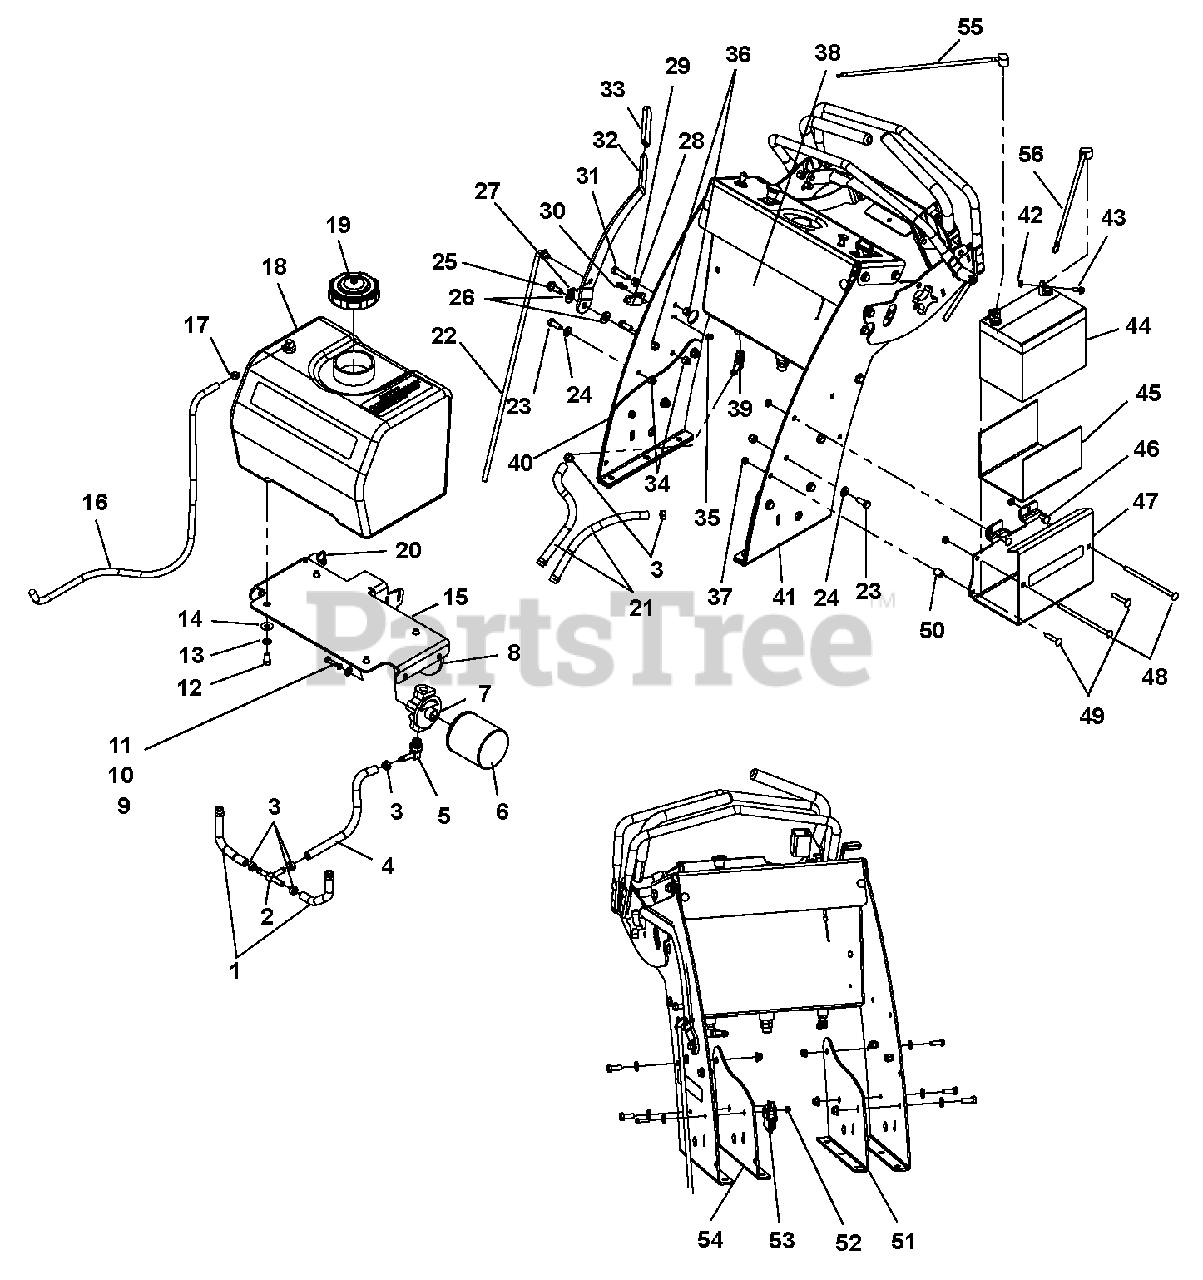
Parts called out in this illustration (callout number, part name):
1	Hose, Hydraulic .375 x 6.00
2	Fitting, TUN .375 Hose
3	Clamp, Hose - 1/2" Pinch
4	Hose, Hydraulic .375 x 10.5
5	Fitting, 90 Deg. Barb-OR
6	Filter, Oil
7	Head, Oil Filter
8	Guard, Hydraulic Filter
9	Washer, .250 Regular Flat
10	Washer, .250 Medium Spring Lock
11	Bolt, .25-20 x 1.00 Hex Grade 5
12	Bolt, .38-16 x .75 Hex Grade 5
13	Washer, .375 Medium Spring Lock
14	Washer, .375 Regular Flat
15	Bracket, Fuel Tank
16	Hose, Fuel .25 x 15.00
17	Clamp, Fuel Line
18	Fuel Tank, Rev B
19	Cap, Fuel
20	Cable Tie, .15 x 8.50
21	Hose, Hyd. .375 x 11.5
22	Rod, Drive Control
23	Bolt, .38-16 x 1.00 Hex Grade 5
24	Washer, .406 x .813 x .065 Flat
25	Bolt, .50 x 1.06 x .375-16 Grade 5
26	Washer, .510 x 1.00 x .068 Nylon
27	Ring, Rue .375 x .054 x 1.254
28	Switch- Double Pole N.O./N.O.
29	Locknut, .375-16 WHIZ
30	Screw, 10-24 x .625 Phillips Head
31	Bolt .38-16 x 1.50 Hex Grade 5
32	Lever, Hand Brake
33	Grip, PVC .250 x 1.00 x 3.63
34	Locknut, .375-16 Nyloc
35	Locknut, 10-24 Nyloc
36	Locknut, .375-16 Center
37	Locknut, .3125-18 Nyloc
38	Weldment, Hydraulic Tank
39	Fitting, 90 .5625 MOR x .375 Hose
40	Weldment, RH Upright Tower 18"
41	Weldment, LH Upright Tower 18"
42	Locknut, .25-20 (988402, 403)
43	Bolt, .25-20 x .625 (988402, 403)
44	Battery, 12V-U1-CCA270 (988402, 403)
45	Strip, Battery Insulator (988402, 403)
46	Bolt, Round Head Square Neck .31-18 x .75 Grade 5 (988402, 403)
47	Tray, Battery (988402, 403)
48	Bolt, .3125-18 x 6.00 Grade 2 (988402, 403)
49	Bolt, .31-18 x 1.75 Round Head Square Neck Grade 5 (988402, 403)
50	Bushing, .364 x .540 x .700 (988402, 403)
51	Plate, Double LH Upright
52	Locknut, .25-20 Nyloc (988400)
53	Module, Electronic (988400)
54	Plate, Double RH Upright
55	Cable, Battery Ground 25" (988402, 403)
56	Cable, Battery Positive 25" (988402, 403)
